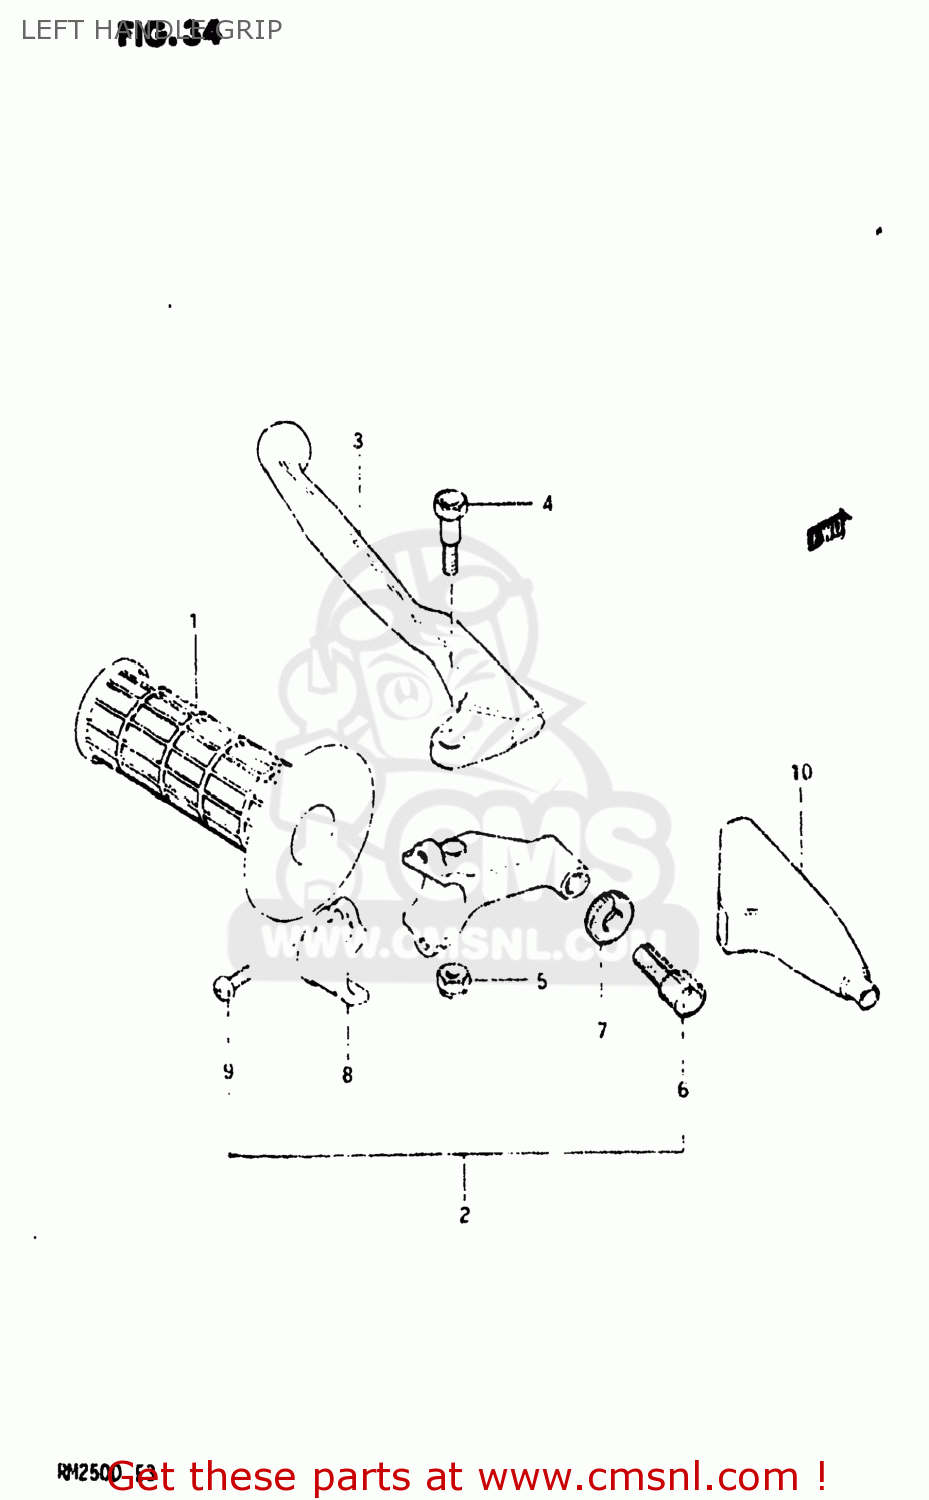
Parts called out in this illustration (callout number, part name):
1	GRIP,LEFT
2	LEVER ASSY,CLUTCH
3	LEVER,CLUTCH
4	BOLT,LEVER
5	NUT 6MM
6	ADJUSTER,CABLE
7	NUT,CABLE ADJUSTER
8	BRACKET,CLUTCH LEVER HOLDER
9	SCREW
10	COVER,CLUTCH LEVER
